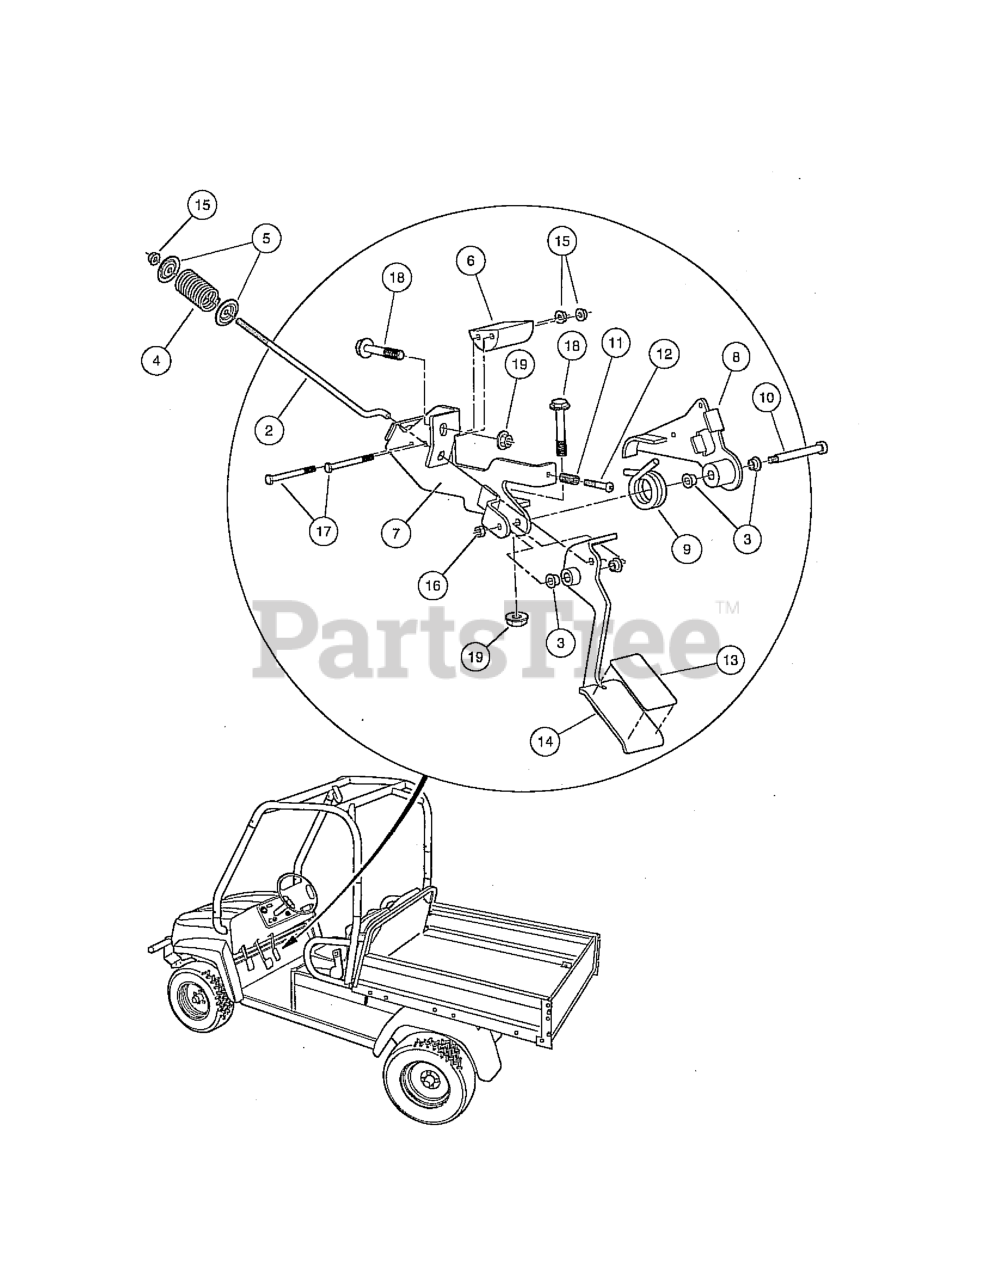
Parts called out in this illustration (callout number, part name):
1	ASM, PEDAL ACCELERATOR
3	BUSHING, GREASELESS
10	BOLT, SHOULDER, M8 X 70
13	PAD, GRIP TAPE, ACCELERATOR
16	NUT M6X1 MECH DEF CENTER
17	BOLT, M6 X 1 X 70
18	BOLT FLG, M8X1.25X65
19	LOCK NUT, FLG M8 X 1.25 NYLON
